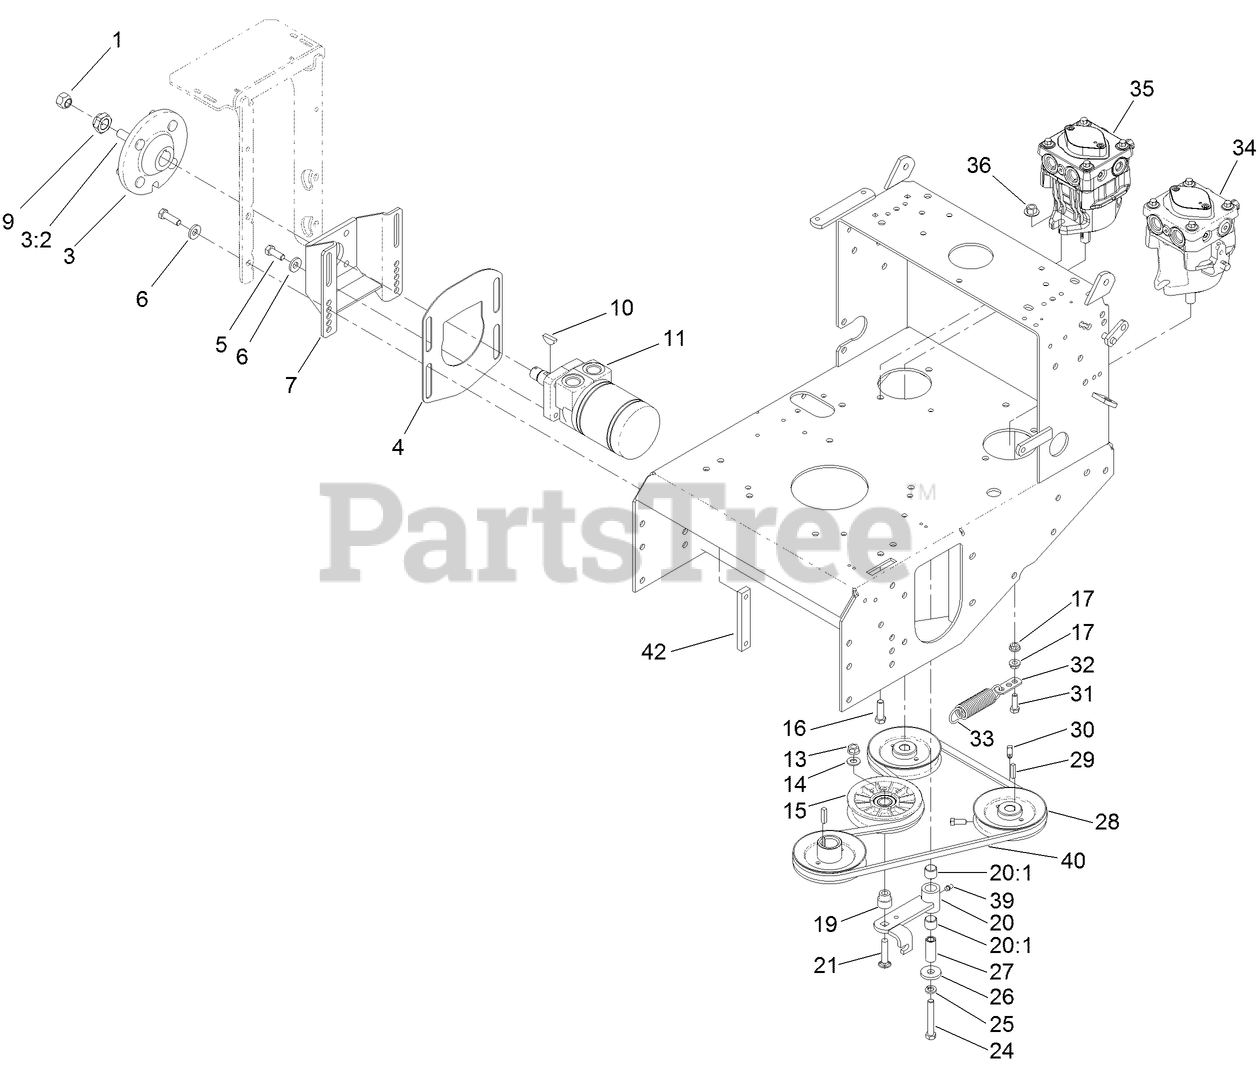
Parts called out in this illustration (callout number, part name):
1	NUT-LUG
3	WHEEL HUB ASM
3:2	STUD-WHEEL
4	GUARD-DEBRIS
5	SCREW-HH
6	WASHER-BELLEVILLE
7	MOUNT-MOTOR
9	NUT-LOCK
10	KEY-WOODRUFF
11	HYD MOTOR ASM
13	NUT-HF
14	WASHER-FLAT
15	PULLEY-IDLER, FLAT
16	SCREW-HH
17	NUT-HF
19	BUSHING-IDLER
20	IDLER ARM ASM
20:1	SLEEVE-BEARING
21	SCREW-CARR
24	SCREW-HH
25	WASHER-LOCK
26	WASHER
27	BUSHING
28	SHEAVE ASM
30	SCREW-SET, SQH
31	SCREW-HH
32	ANCHOR-SPRING
33	SPRING-EXTENSION
34	LH HYD PUMP ASM
35	RH HYD PUMP ASM
36	NUT-FLANGE
39	FITTING-GREASE
40	V-BELT
42	BAR-NUT
